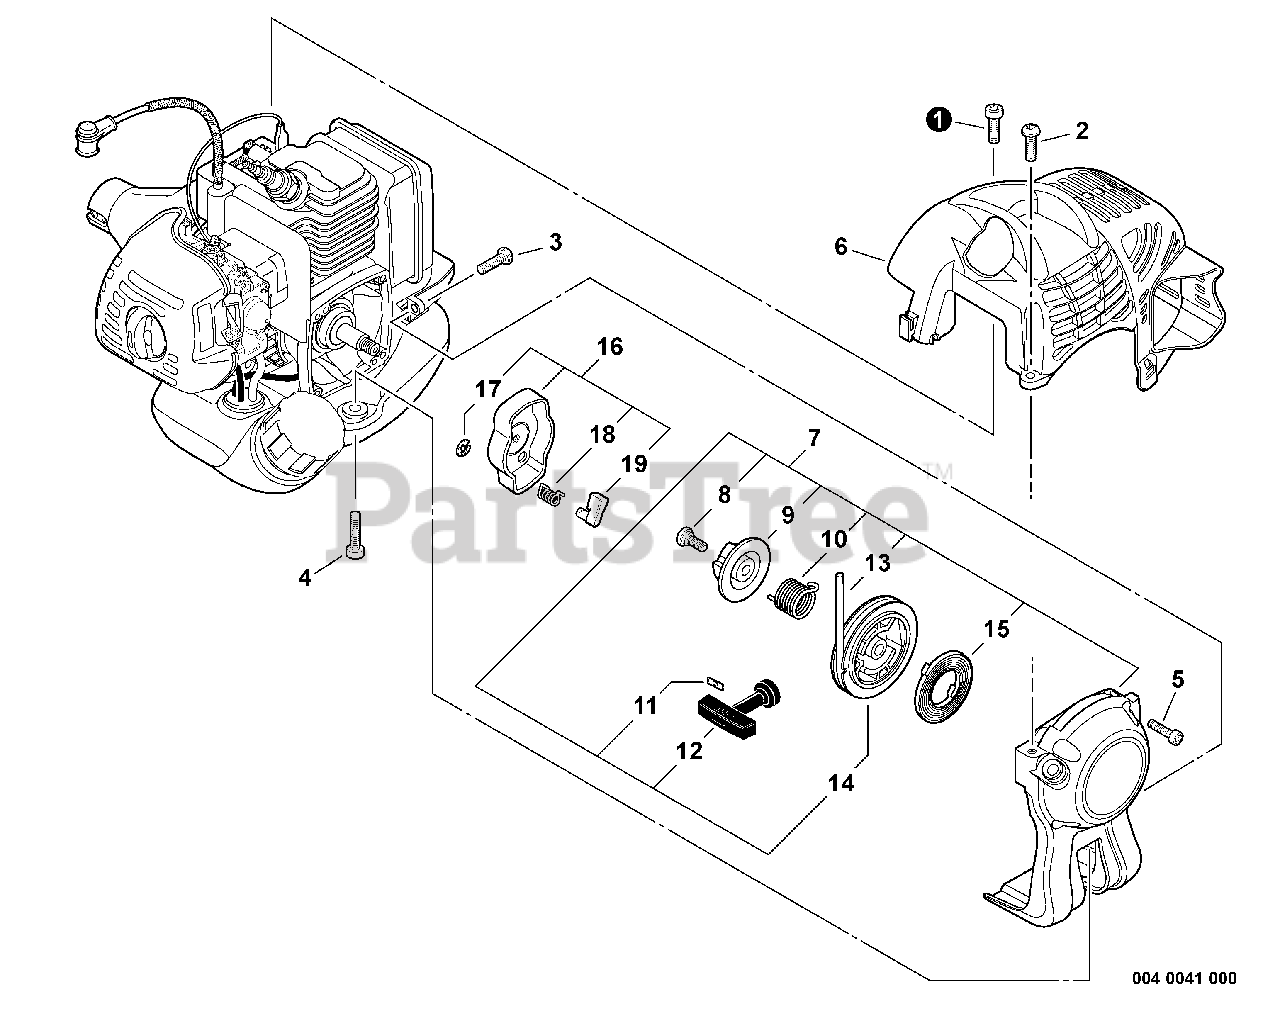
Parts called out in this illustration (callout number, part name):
1	BOLT, TORX 5×16
2	BOLT, TORX 5×16
3	BOLT, TORX 5×16
4	BOLT, TORX 5×20
5	BOLT, TORX 4×16
6	COVER, ENGINE
7	STARTER ASSY, RECOIL
8	SCREW
9	PLATE, CAM (NLA SEE PB 15-06)
10	SPRING, TORSION
11	RETAINER, ROPE
12	GRIP, STARTER
13	ROPE, STARTER
14	REEL, ROPE
15	SPRING, RECOIL
16	PAWL ASSY, STARTER
17	E-RING 4
18	SPRING, RETURN
19	PAWL, STARTER
